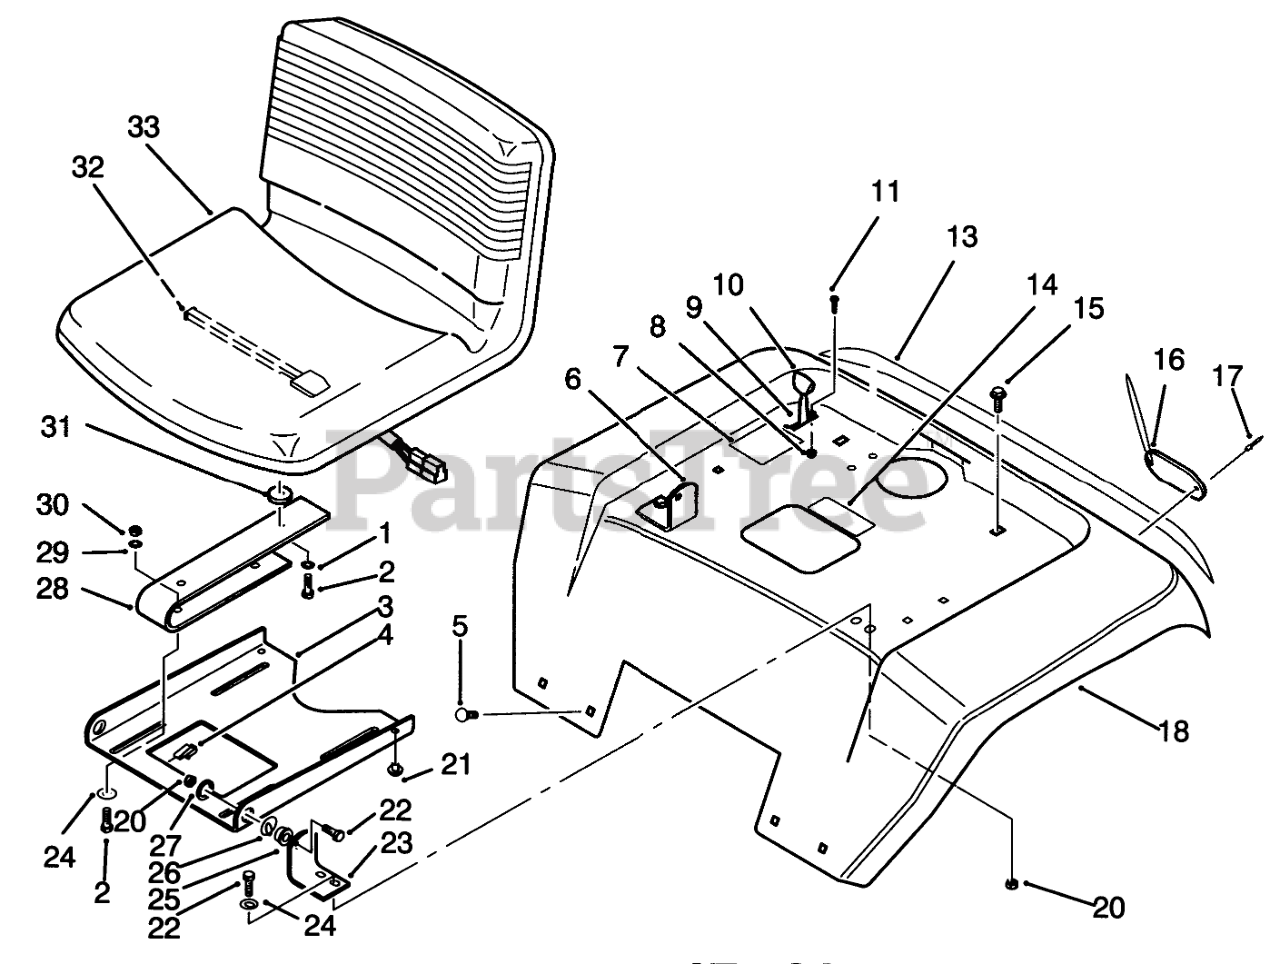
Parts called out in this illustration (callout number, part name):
1	Lockwasher
2	SCREW-HH
3	Plate-SeatPivot
4	J-CLIP
5	SCREW-CARR
6	Bracket-Pivot RH
7	DECAL-PUSH
8	Nut
9	CONTROL-PUSH VALVE
10	KNOB-THROTTLE
11	SCREW
13	DECAL-FENDER
14	DECAL - DANGER
15	Screw
16	Reflector
17	Poprivet
18	Fender & Safety Decal Assy. (Incl. Ref. #14)
20	NUT-LOCK, NI
21	BUMPER-RUBBER
22	SCREW-HH
23	BRKT-PIVOT L.H. B
24	WASHER-PLAIN
25	BUSHING
26	WASHER-SPECIAL
27	WASHER-SPRING
28	Seat Spring
29	WASHER-PLAIN
30	NUT-LOCK, NI
31	SPACER-NYLON
32	SWITCH-SEAT
33	SEAT V-510
